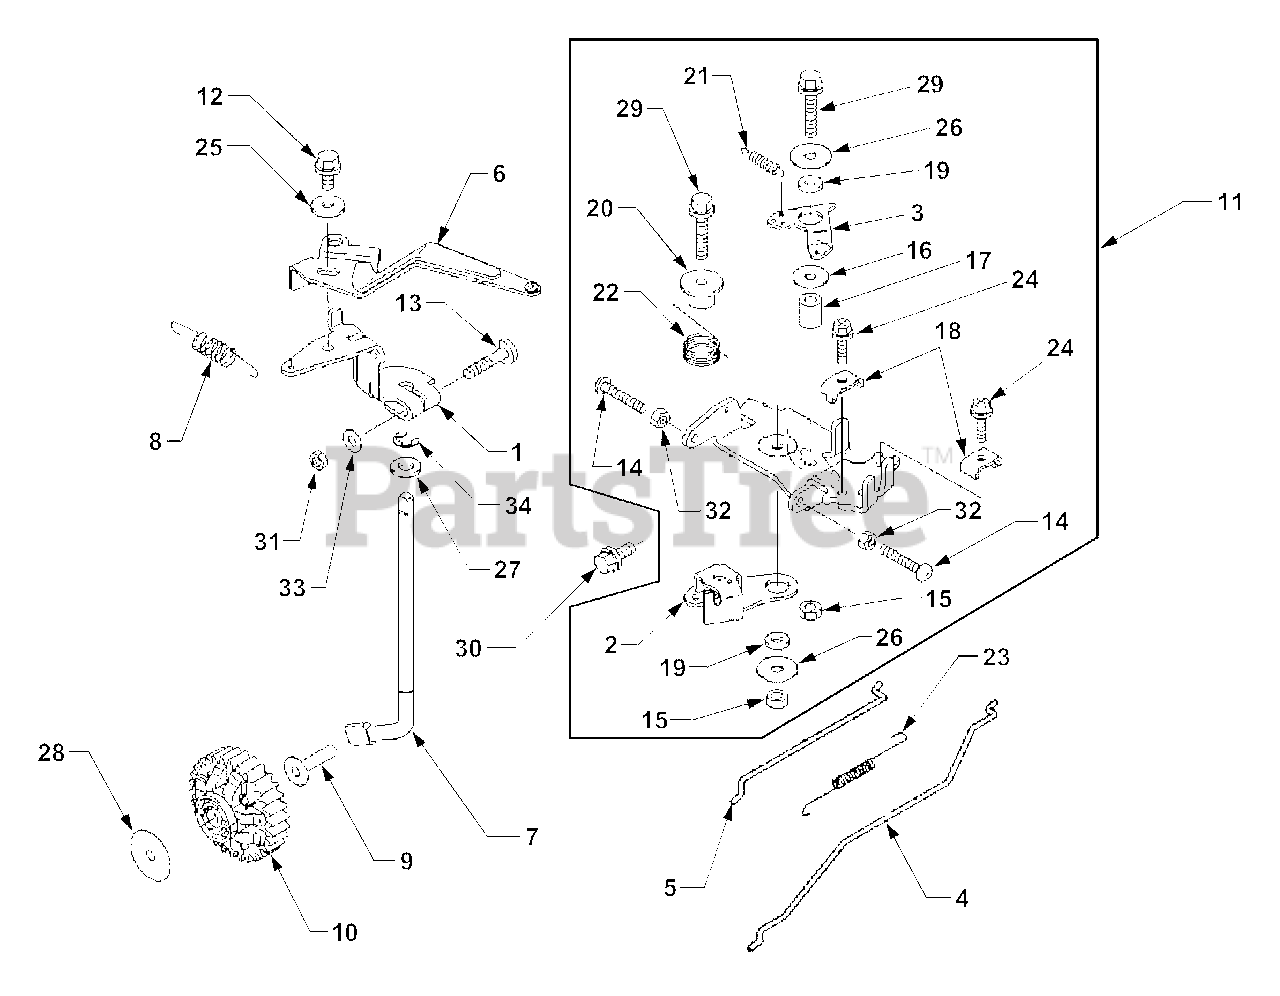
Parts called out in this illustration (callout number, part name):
2	Lever, Throttle
6	Arm Assembly
7	Arm, Governor Pivot
8	Spring, Governor
10	Gear Assembly, Governor
11	Panel, Control Complete
12	Bolt
14	Screw, 5 x 30
16	Washer, 6 x 19 x 1.2
19	Collar, 6 x 13 x 2.3
26	Washer, 6.5 x 22 x 1.2
27	Washer, 8.3 x 16 x 2.3
28	Washer, 6.2 x 30 x 0.5
29	Bolt, Flanged
30	Bolt, Flanged
31	Nut, Hex
33	Washer, Plain
34	Circlip, E-Ring
